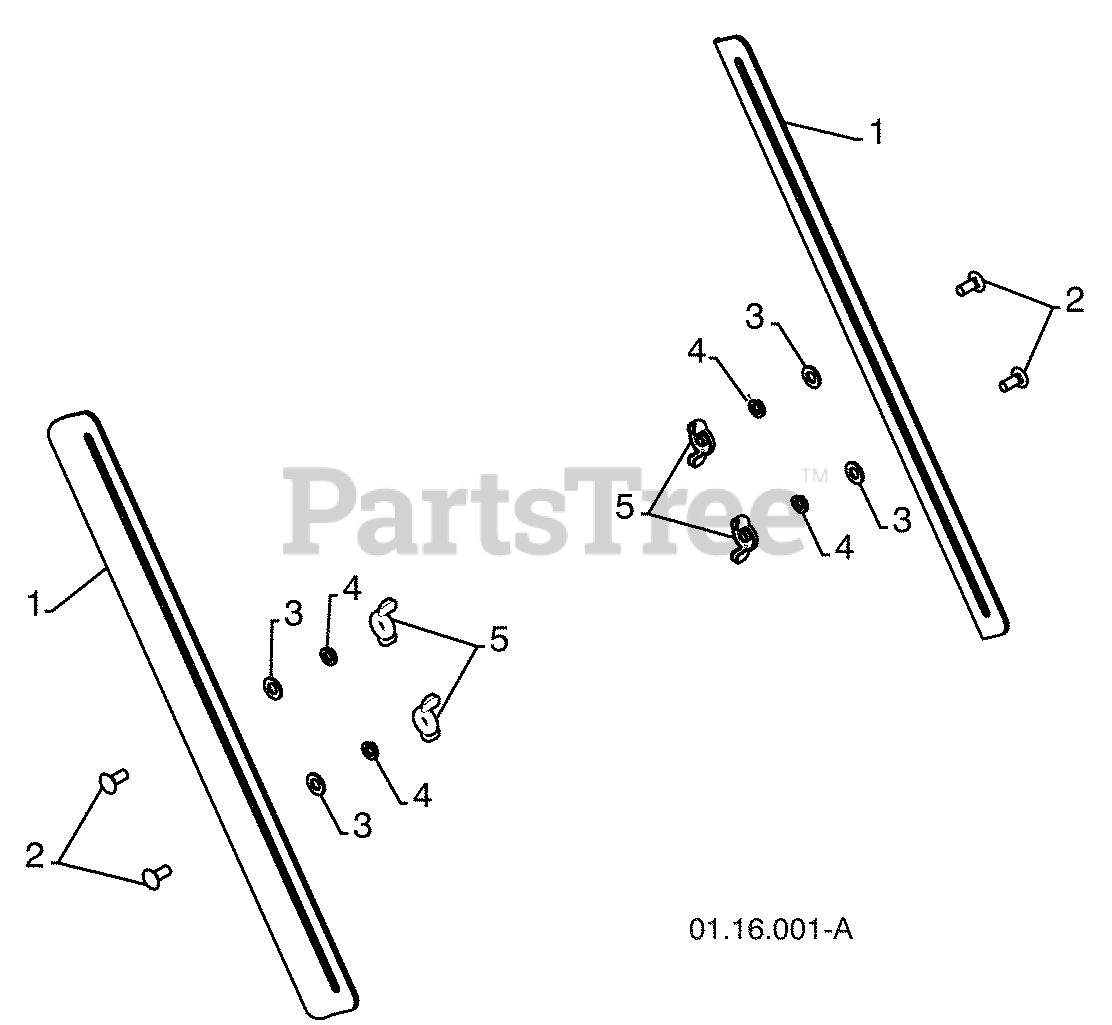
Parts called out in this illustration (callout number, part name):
1	DRIFT CUTTER BAR
2	CARRIAGE BOLT 5/16?18 X .750
3	PLASTIC WASHER
4	LOCKWASHER 5/16
5	NUT 5/16--18
